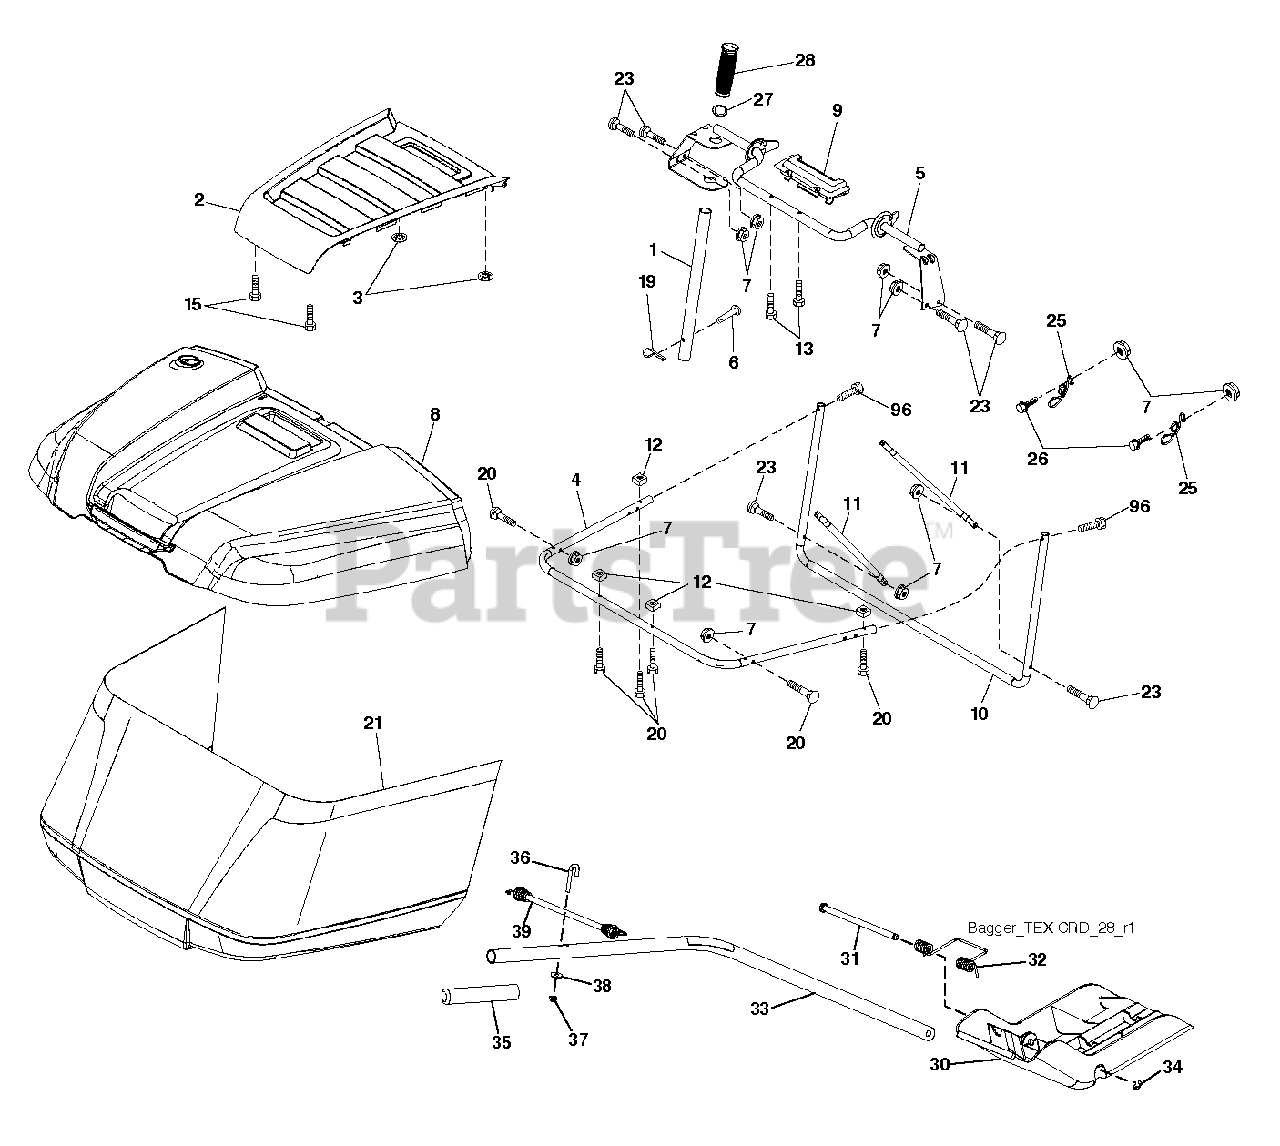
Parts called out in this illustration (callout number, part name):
1	TUBE.HANDLE.BAGGER.CRD/SRD.BLA
2	APPLIQUE.TOP.BAG.SRD.ORANGE
3	NUT.PUSH.156
4	SUBASM.TOP.BAGGER.TUBE
5	FRAME.ASM.TOP.BAGGER.SRD
6	RIVET,DRILLED
7	NUT T
8	BAGGER.TOP.SRD.APPLIQUE
9	INSERT.HANDLE.BAGGER.(2 2)
10	FRAME FRAME.FRONT.TEX.CRD
11	BRACE BRACE SIDE TUBE
12	NUT.SQUARE.1/4
13	SCREW.1/4X1.150.HXWSH
15	SCREW,#8.FLAT.HEAD.DRILL.TIP
19	PIN.COTTER.5/16.BOW TI
20	SCREW.HEXCAP.1/4-20X1.375(2 2)
21	BAG SUBASM. TEX CRD GEN 2 HUSQ
25	SPRING.LATCH.BAGGER.SRD
26	SCREW HEX CRT
27	RB GROMMET.RUBBER.SRD
28	GRIP.HANDLE.BLACK
30	PLUG PLUG
31	PIN PIN.HINGE
32	SPRING SPRING DOUBLE TORSION
33	SHAFT SHAFT TEX CRD MULCH PLU
34	E-RING.5/16"
35	GRIP GRIP MULCH PLUG HAND
36	BOLT BOLT J
39	BUBGEE BUBGEE TEX CRD
96	SCREW.HEXCAP.1/4X-20X1.500
